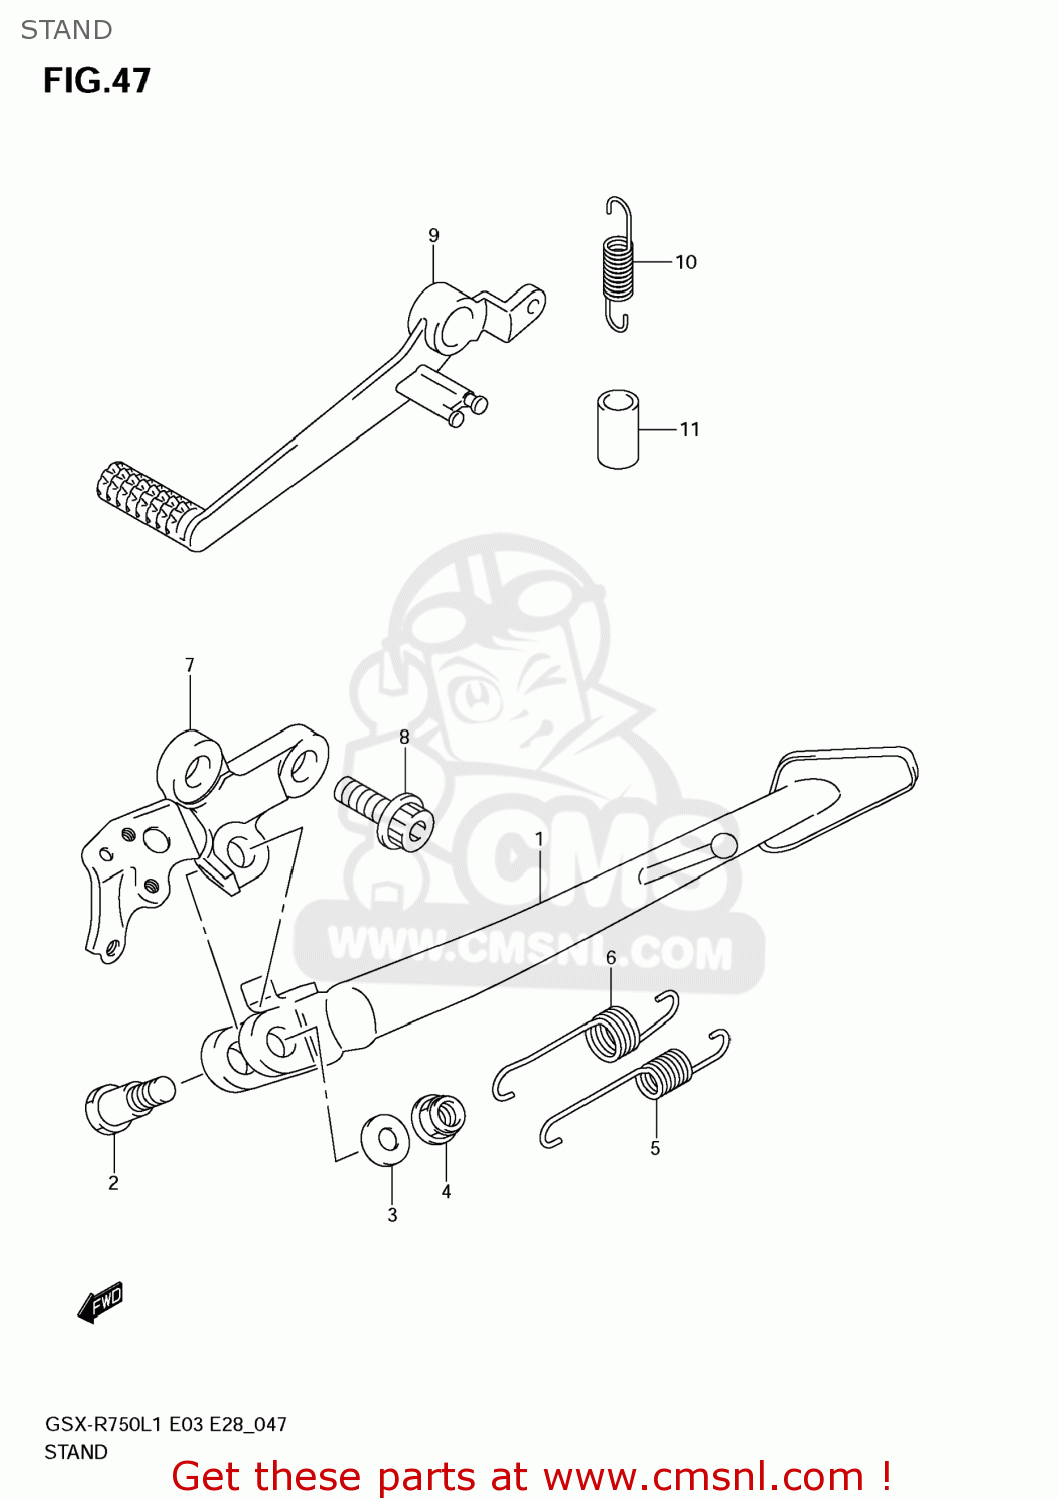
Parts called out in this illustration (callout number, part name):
1	STAND,PROP
2	BOLT,PROP STAND
3	SHIM(16X28X0.5)
4	NUT
5	SPRING
6	SPRING
7	BRACKET COMP,P
8	BOLT(10X28)
9	PEDAL,BRAKE
10	SPRING
11	HOSE(11X15X600)
